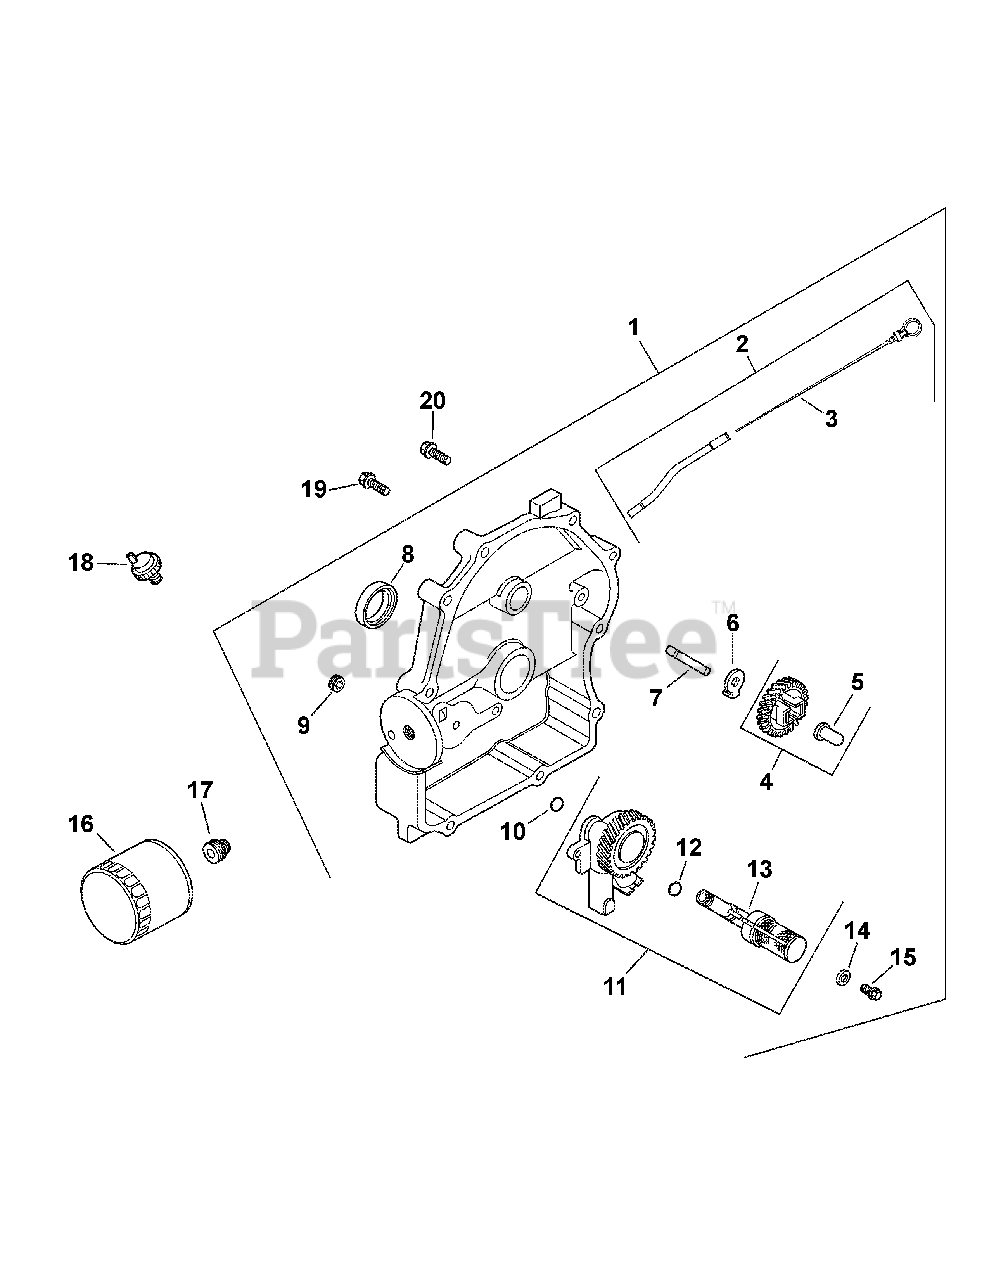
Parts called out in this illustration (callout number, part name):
1	Plate, closure ass’y (Incl. 2-15)
2	Kit, tube w/dipstick (Includes 3)
4	Kit, governor gear (Includes 5)
5	Pin, governor regulating
7	Shaft, governor gear
8	Seal, oil (PTO end)
9	Plug, pipe 1/8"
11	Oil pump ass’y (Includes 12,13)
12	O-Ring, oil pick-up
13	Pick-up, oil
14	Washer, plain 6 mm
15	Screw, hex flange M6x1.0x25
17	Nipple, oil filter
18	Switch, pressure
19	Screw, hex flg, M8x1.25x45
20	Screw, hex. flange M8x1.25x45
